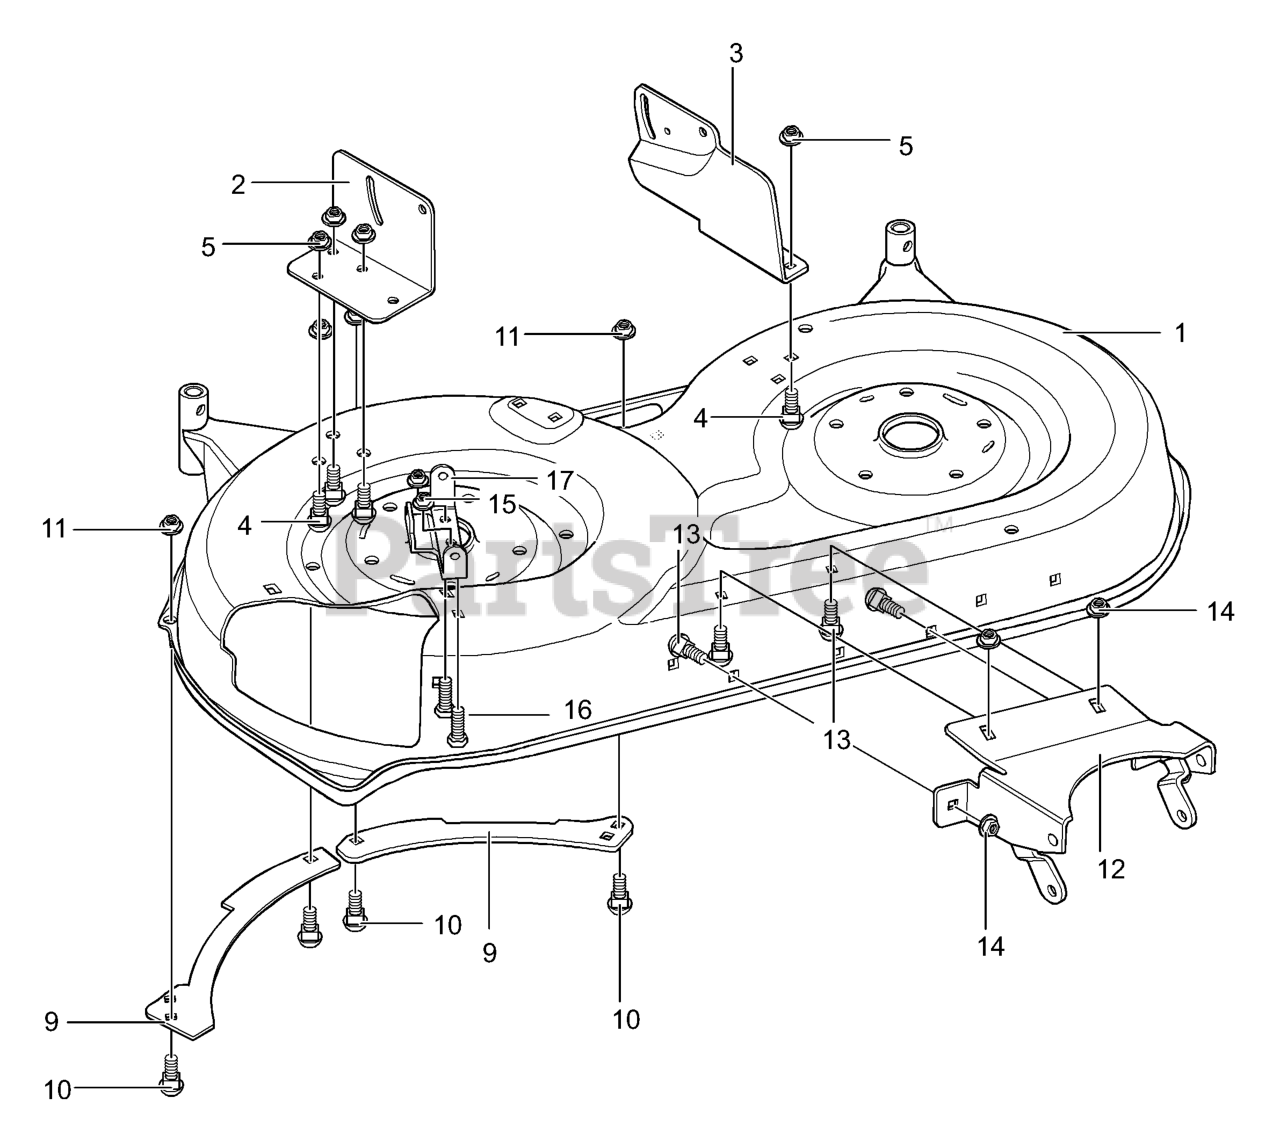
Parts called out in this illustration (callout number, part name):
1	42" BLADE HOUSING
2	BRACKET, DECK RH
3	BRACKET, DECK LH
4	BOLT, .31-18X0.62
5	NUT, .32-18 FLANGELOCK
9	PLATE, REAR TOEGUARD
10	BOLT, .31-18X0.62
11	NUT, .32-18
12	BRACKET, FRONT DECK
13	BOLT, .31-18X0.62
14	NUT, .31-18 FLANGELOCK
15	NUT, .32-18
16	BOLT, .31-18X0.62
17	BRACKET, CHUTE DEFLECTOR
